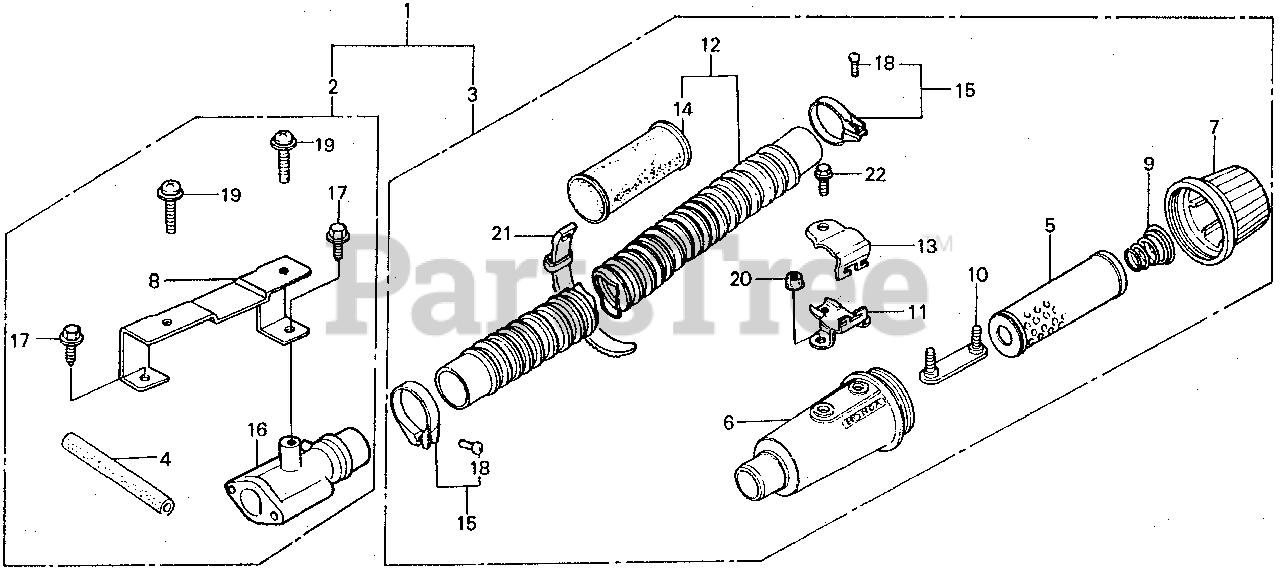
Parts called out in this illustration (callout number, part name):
1	AIR CLEANER KIT, SNORKEL JOINT
2	JOINT KIT, SNORKEL AIR CLEANER (Honda Code 0905729). (N/A: SEE COMPONENTS)
3	AIR CLEANER KIT, SNORKEL (N/A: SEE COMPONENTS)
4	TUBE, BREATHER
5	ELEMENT, AIR CLEANER
6	HOUSING, AIR CLEANER
7	CAP, AIR CLEANER
8	STAY, CARBURETOR COVER
9	SPRING, SETTING
10	PLATE, AIR CLEANER SETTING
11	BRACKET A, AIR CLEANER
12	HOSE, AIR CLEANER
13	BRACKET B, AIR CLEANER
14	PROTECTOR, HOSE
15	BAND, AIR CLEANER CONNECTING TUBE (34)
16	JOINT, TUBE CONNECTING
17	BOLT, FLANGE (6X12) (CT200)
18	SCREW, PAN (4X25)
19	SCREW-WASHER (6X25) (Honda Code 0802538). (NOT AVAILABLE)
20	NUT, FLANGE (6MM)
21	BAND B3, CABLE HARNESS
22	BOLT, FLANGE (6X16) Use from Engine SN 2056820.
